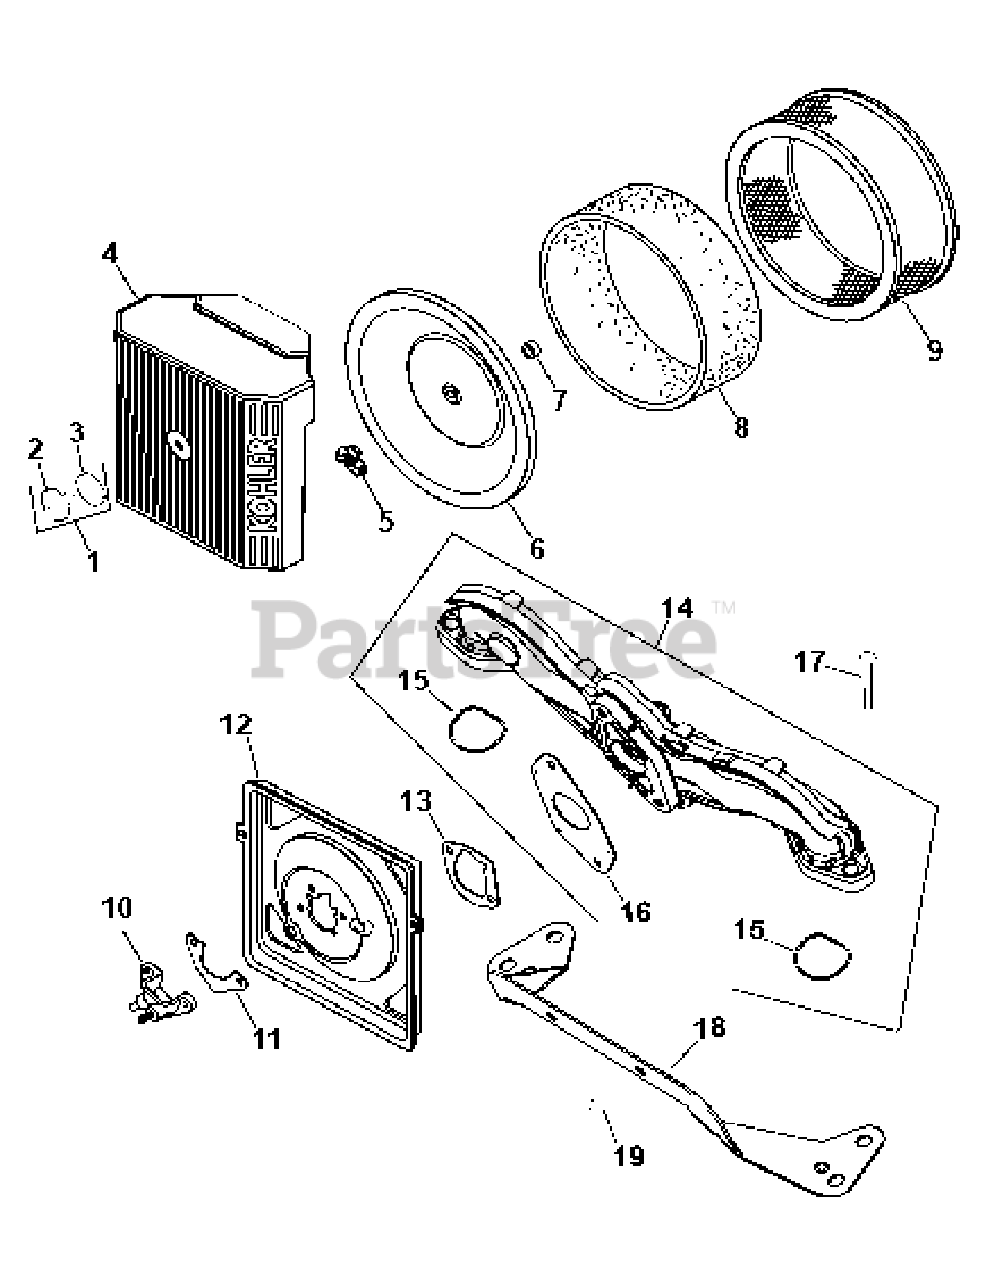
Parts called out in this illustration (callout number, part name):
1	Knob With Seal Kit
4	Air Cleaner Cover
6	Inner Air Cleaner Cover
7	Inner Air Cleaner Seal
8	Precleaner Element
9	Air Cleaner Element
10	Spit Back Cup w/Stud
11	Spit Back Cup Gasket
12	Air Cleaner Base
13	Air Cleaner Gasket
14	Intake Manifold
15	Intake Port O-Ring
16	Carburetor Gasket
17	Hex Flange Screw (M6 x 1.0 x 40)
18	Air Cleaner Bracket
19	Hex Flange Screw (M5 x .8 x 10)
